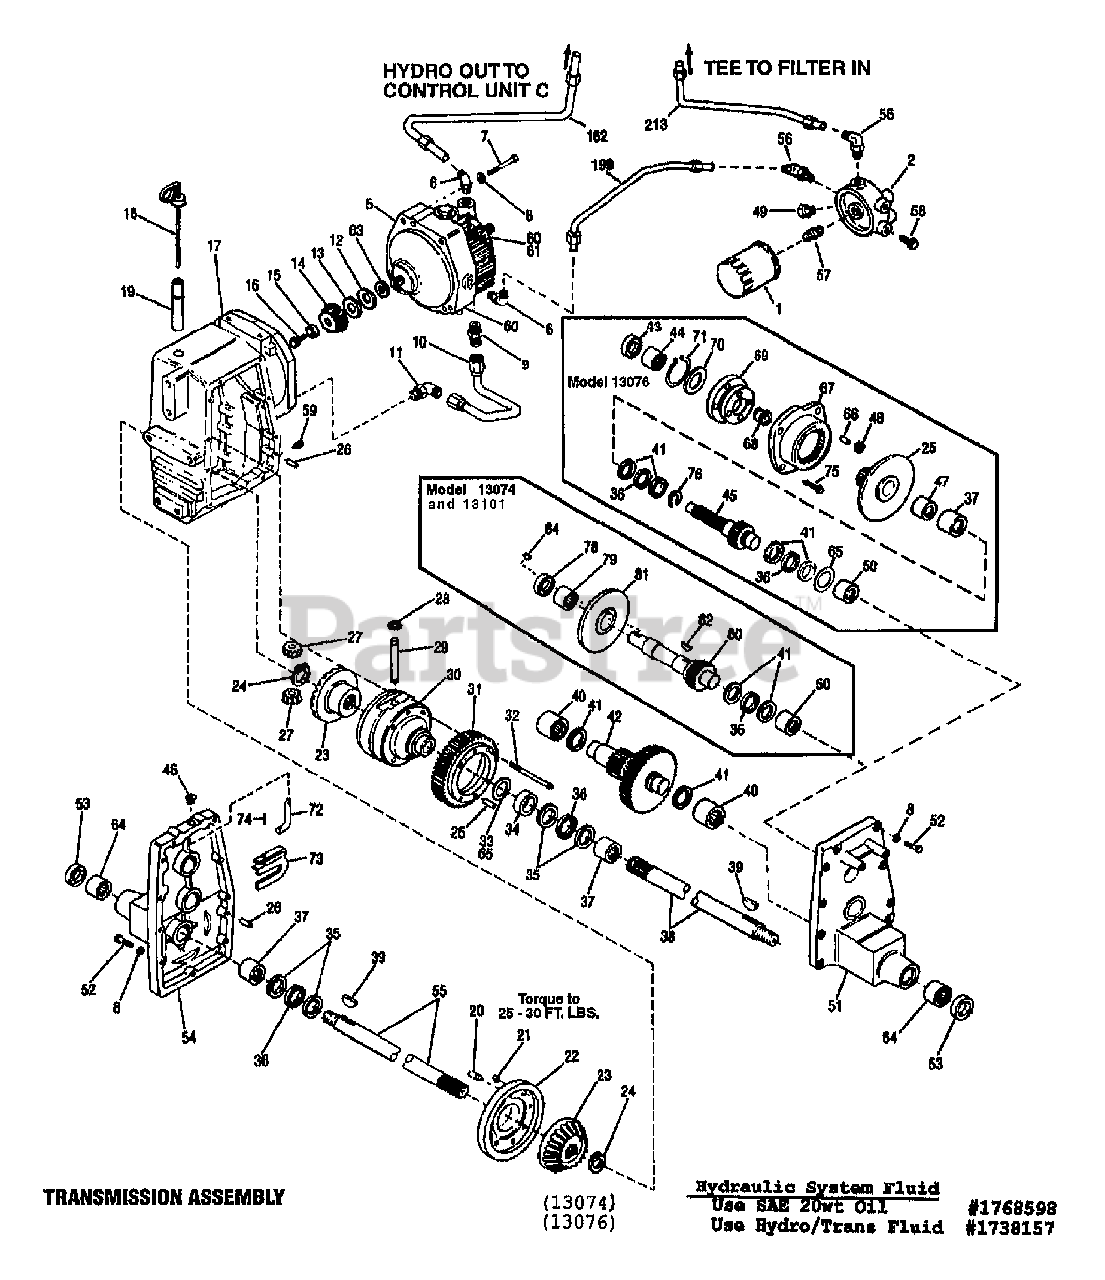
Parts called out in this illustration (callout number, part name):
1	FILTER-OIL
2	FILTER-MANIFOLD
5	PUMP-HYDRO
6	ELBOW
7	SCR-HH 3/8-16X2.75 G5 ZP
8	WASHER-LK .375 @ DEPL
9	CONNECTOR
11	ELBOW
12	WASHER-SHIM
13	WASHER-SHIM
14	PINION-BEVEL
15	SPACER-1.0X.25X.25
16	SCR-HH 1/4-20X.625 G5 ZP
17	HOUSING-TRANSAXLE
18	DIPSTICK
20	PIN-.312X.75
21	NUT-HEX/LK 5/16-18 G5ZP
22	COVER-DIFFERENTIAL
23	GEAR-BEVEL 22T
23	GEAR-23T
24	RING-RET
24	RING-HEAVY EXT HD 1.0 ID
25	GEAR-BEVEL 23T 24T 56T
26	PIN-DOWEL .375X1.00 ZP
27	PINION-10T
28	RING-HEAVY EXT .625 ID
29	PINION-SHAFT
30	CARRIER-DIFFERENTIAL
31	GEAR-AXLE 47T
32	SCR-HFLK 5/16-18X4.00 ZP
33	SHIM-1.75X1.26X.02
33	SHIM-.005
33	SHIM-1.875X1.013X.015
34	SPACER-1.75X1.265X.432
34	SPACER-1.5X1.01X.45
35	RACE-THRUST
36	BEARING-THRUST
37	BEARING-NEEDLE
38	AXLE-RH
39	KEY-WOODRUFF .312X1.12
40	BEARING-NEEDLE
41	RACE-THRUST
42	GEAR CLUSTER
42	ASSM-GEAR CLUSTER
43	SEAL-OIL
44	BEARING-NEEDLE
45	SHAFT-PINION
46	SEAL-OIL
47	BEARING-BRONZE
48	GEAR-PLANET
49	SWITCH-TEMPERATURE
50	BEARING-NEEDLE
51	COVER-TRANS RH
51	COVER-TRANSAXLE RH
52	SCR-HH 3/8-16X1.5 G5 ZP
53	SEAL-OIL
54	COVER-TRANS LH
55	AXLE-LH
56	ELBOW
57	COUPLING
59	PLUG-PIPE
60	SEAL-OIL
61	SHIELD-GRASS
63	WASHER-1.0X.64X.029
64	BEARING
64	BEARING-NEEDLE
65	SHIM-.005
67	GEAR-INTERNAL RING
68	GEAR-SLIDING
69	CARRIER-PLANET
70	WASHER-THRUST
71	RING-RET. INT 4 DIA
72	SHAFT-SHIFTER
73	PLATE-SHIFTER
74	PIN-ROLL .156X.75
75	SCR 5/16-18X1.00
76	RING-POSITIONING
78	SEAL-OIL
79	BEARING-NEEDLE
80	ASSM-PINION SHAFT
82	KEY-WOODRUFF .25X1
84	KEY-WOODRUFF .25X.75
162	TUBE-HYDRO PRESSURE
199	ASSM-RETURN TUBE
213	ASSM-TUBE
